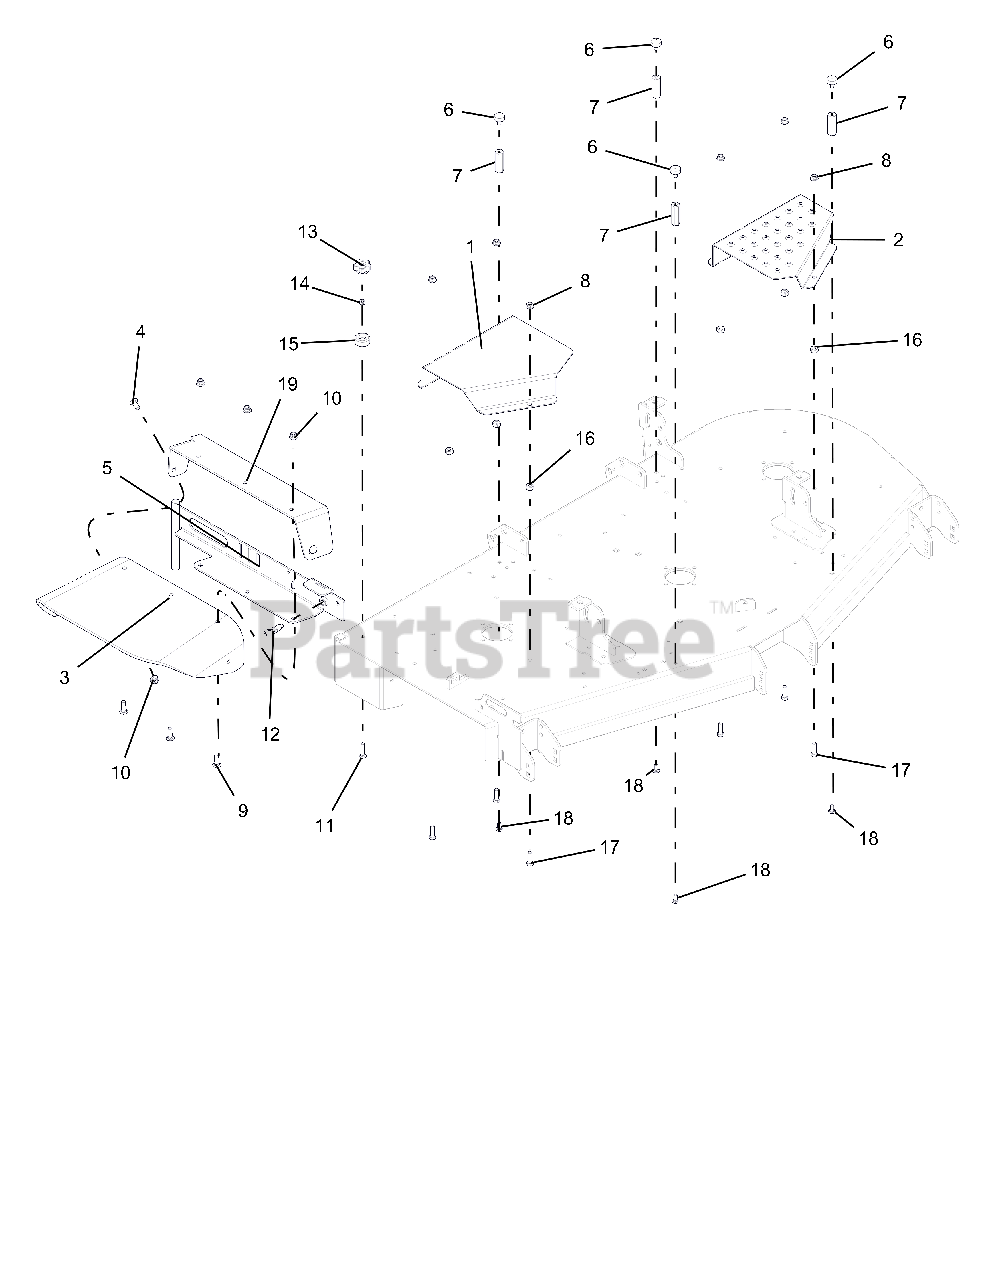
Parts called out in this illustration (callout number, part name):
1	GUARD, 60"-66" RH DECK BELT-BLACK
2	GUARD, 60" LH DECK BELT-BLACK
3	CHUTE, RUBBER DISCHARGE
4	BLT-RDHDSQNK .38-16X1.00 G5 YWZC
5	WLDMT, 52"-60" DISCH CHUTE MTG-RED
6	BUMPER, RUBBER
7	NUT, .31-18 X 2.25 LG COUPLING
8	@NUT-SPNLK-FLG .375-16 YWZC
9	BLT-RDHDSQNK .38-16X1.25 G5 YWZC
10	NUT-LK-NYL-FLG .38-16 YWZC
11	BLT-RDHDSQNK .31-18X1.50 G5 YWZC
12	PULL PIN,.50-13THDX.310 PLNGR
13	KNOB, CLAMPING
14	NUT-LK-CTR .31-18 YWZC
15	BUMPER, RECESSED 1.50 X .63 W/.31 HOLE
16	NUT-HEAVY HEX .38-16 YWZC
17	BLT-HEX .38-16X1.25 GR5 YWZC
18	BLT, RDHDSQNK .31-18X.75 LOCTITE
19	DISCHARGE CHUTE SUPPORT W/SAFETY DECAL-RED
